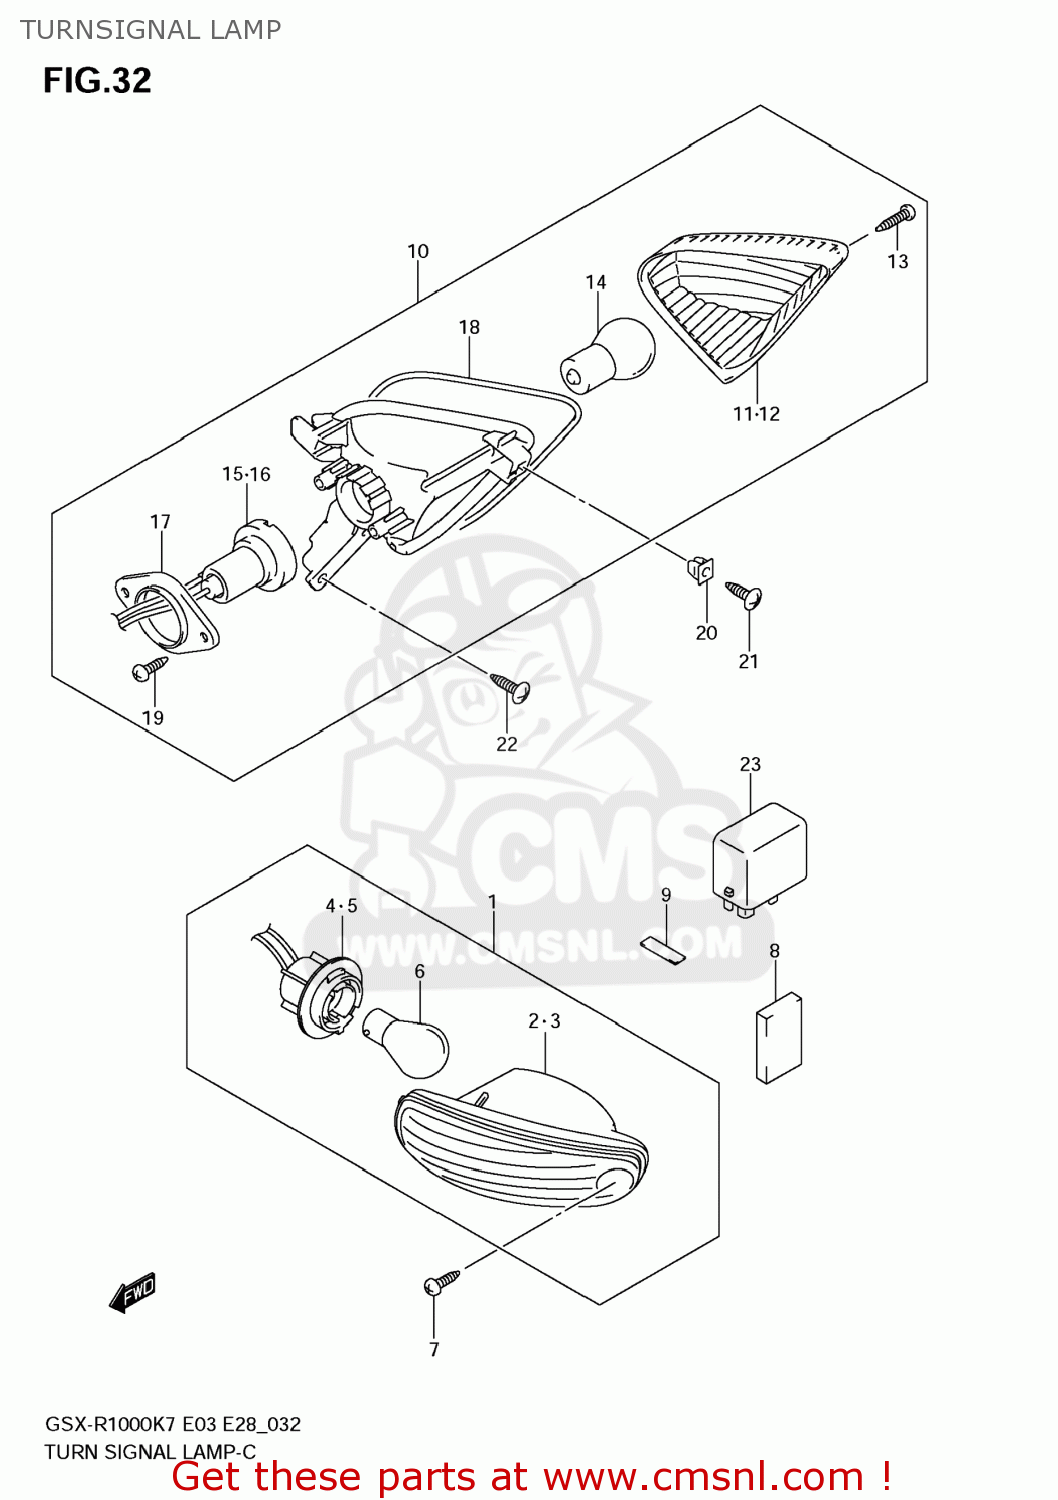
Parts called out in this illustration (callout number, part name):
1	LAMP ASSY,FR TURN SIGNAL,R
2	LAMP UNIT,R
3	LAMP UNIT,L
4	SOCKET,R
5	SOCKET,L
6	BULB(12V21W,AMBER)
7	SCREW(4X20)
8	PROTECTOR(50X50X5)
9	TAPE,FR TURNSIGNAL
10	LAMP ASSY,RR TURNSIGNAL,R
11	LENS,R
12	LENS,L
13	SCREW
14	BULB(12V21W,AMBER)
15	SOCKET & CORD,R
16	SOCKET & CORD,L
17	PLATE,RR COMBINATION
18	GASKET (NAS)
19	SCREW
20	NUT
21	SCREW
22	SCREW
23	RELAY ASSY,TURNSIGNAL LAMP
